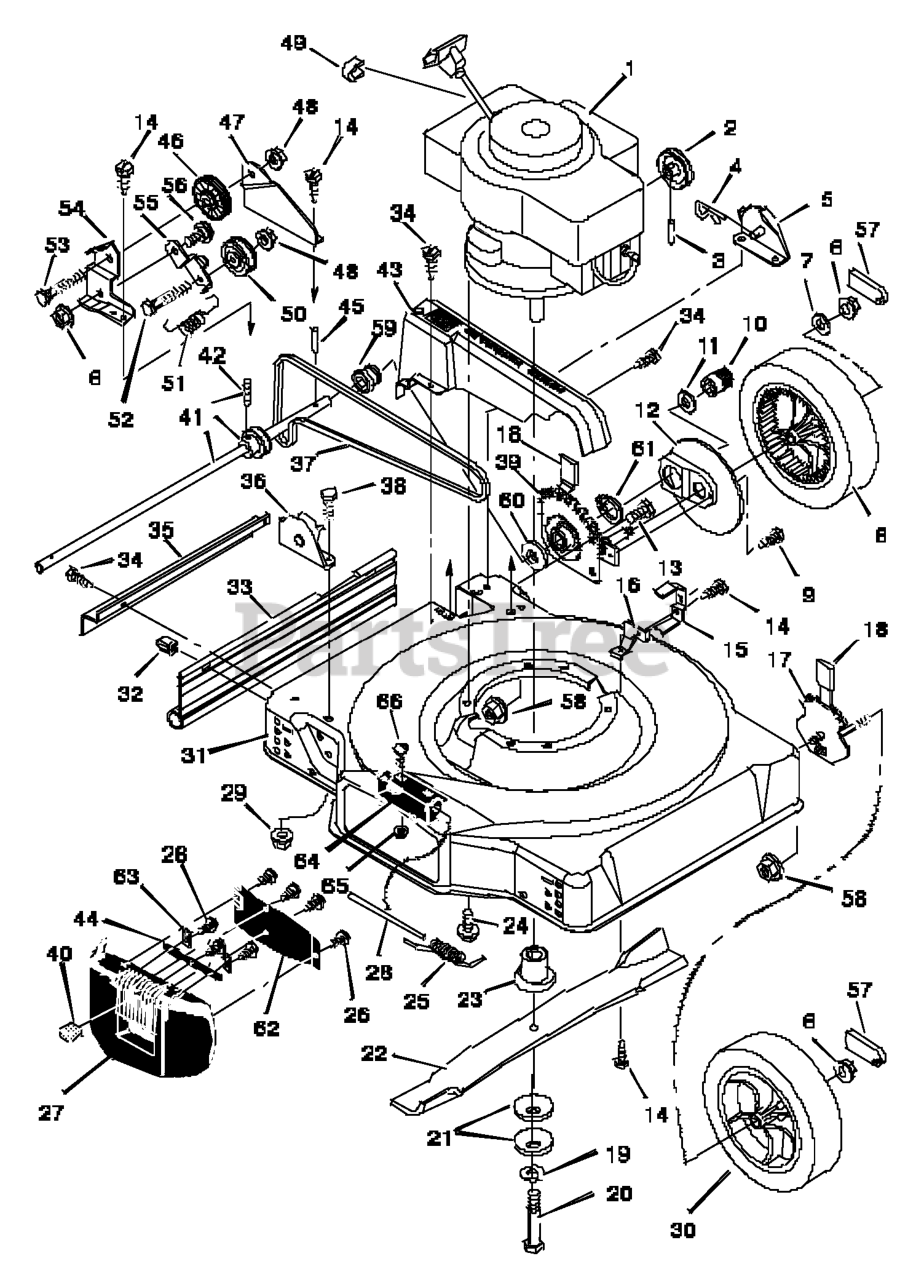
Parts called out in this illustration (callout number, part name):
1	Engine *
3	Pin, Spring
4	Pin, Hair
5	Bracket, Left Handle
6	Nut
7	Washer
8	Wheel, Drive
10	Gear, Right Pinion
12	Cover, Dust
13	Bolt, Hex
15	Guide, Belt
16	Belt Guide, Briggs
17	Height Adjuster, Front
21	Washer, Belleville
23	Adapter, Blade
24	Bolt, Engine
25	Spring, Torsion
27	Deflector, Chute
29	Nut
30	Wheel and Tire, Front
31	Housing
32	Retainer
33	Deflector, Rear
35	Guard, Axle
36	Bracket, Right Handle
37	Belt, Briggs & Stratton
39	Height Adjuster, Left
40	Knob, Latch
41	Axle, Pulley & Setscrew
42	Setscrew
43	Belt Guard, Briggs
44	Latch, Lock
45	Pin, Drive
46	Pulley, Idler
47	Support, Idler
48	Nut
49	Stop, Rope
50	Pulley, Idler
51	Spring, Extension
52	Bolt, Hex
53	Bolt, Hex
54	Bracket, Idler
55	Arm, Idler
56	Bolt, Shoulder
57	Cap, Hub
58	Nut, Flange
59	Bearing and Retainer
60	Washer, Belleville
61	Retainer Ring
63	Retainer
64	Bracket, Deflector
65	Locknut, Flange
66	Bolt, Carriage
